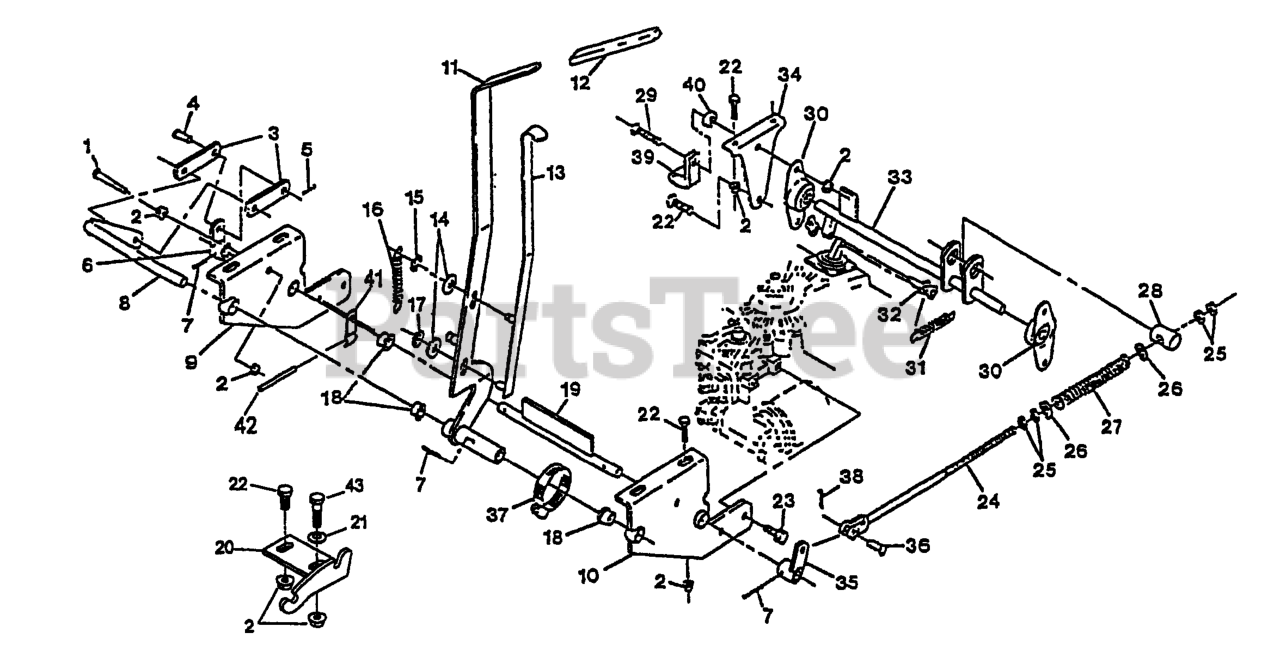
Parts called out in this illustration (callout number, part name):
1	SCREW-HH
3	LINK,BRAKE PLTD
4	PIN-CLEVIS
5	PIN-COTTER
6	WLD,CONTROL ARM
8	PIVOT - BRKT/LEVER
10	WLD,TRANSAXLE SUPPORT RH
11	LEVER,PARK BRK W/DECAL
12	GRIP-LEVER
14	WASHER-PLAIN
15	RING-RETAINING, EXT
16	SPRING,BRAKE HANDLE
17	NUT,PUSH
18	BEARING-CONTROL
19	WLD,BUTTERFLY
20	WLD,BRAKE QUADRANT
21	WASHER-SPRING
22	SCREW-HH
23	SCREW-HHF
24	LINKAGE,BRAKE
25	NUT-HJ
26	WASHER-FLAT
27	SPRING,COMPRESSION
28	PIN,TRUNION
29	SCREW-HH
30	FLANGE MTG, SIDE
32	LINK,CONNECTING
33	WLD,BRAKE JACKSHAFT
36	PIN-CLEVIS
37	CLAMP-HOSE
38	PIN-COTTER
40	SPACER,CLUTCH ANCHOR
41	SPRING,DUMP VALVE
42	ROLLPIN PLTD
43	SCREW-HH
